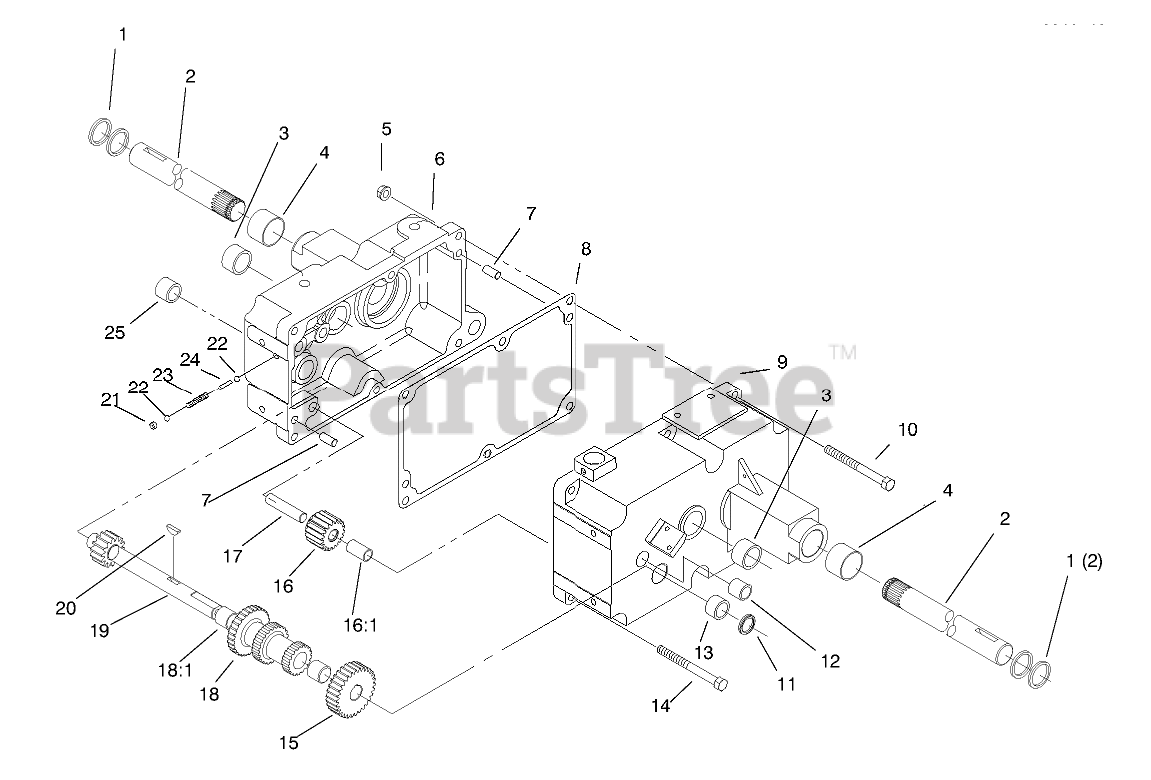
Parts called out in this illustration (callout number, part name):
1	SEAL-OIL
2	AXLE-REAR
3	BEARING-NEEDLE
4	BEARING
5	NUT-LOCK, NI
6	CASE-RH TRANS
7	PIN-DOWEL
8	GASKET-TRANSMISSION
9	Case-Trans
10	SCREW-HH
11	SEAL-OIL
12	BEARING-NEEDLE
13	BEARING-NEEDLE
14	SCREW-HH
15	GEAR-CLUSTER SHAFT
16	GEAR/BUSHING ASM-REVERSE IDLER
17	PIN-DIFFERENTIAL
18	GEAR-CLUSTER
19	SHAFT-CLUSTER
21	CUP-PLUG
22	BALL-DETENT
23	SPRING-SHIFT STOP
24	PIN-SHIFT
25	BEARING-NEEDLE
25:1	Shift Lever
25:2	Shaft-Lever
